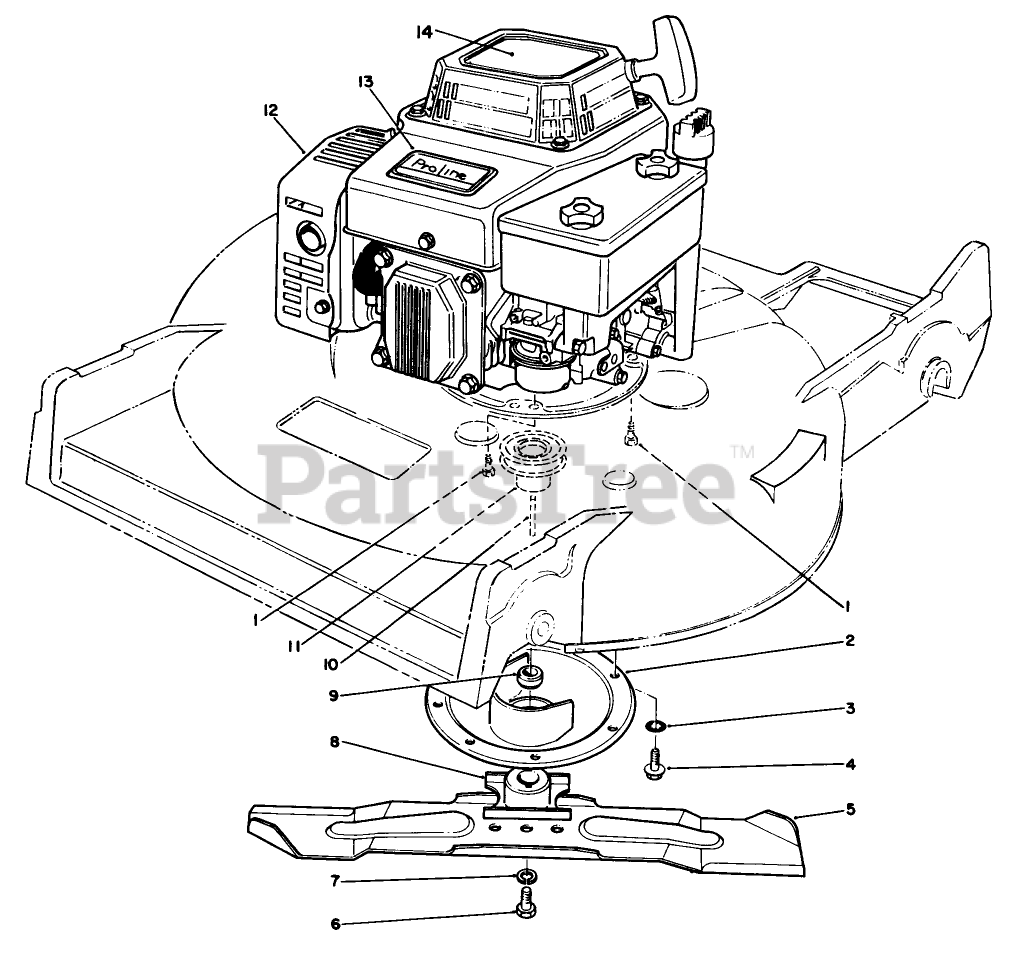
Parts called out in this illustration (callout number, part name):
3	WASHER-LOCK, INTERNAL
4	SCREW-HWHTF
6	SCREW-BLADE
7	WASHER-LOCK
9	SPACER-BLADE RETAINER
10	KEY-SQUARE
11	PULLEY-DRIVER
13	DECAL - PROLINE
